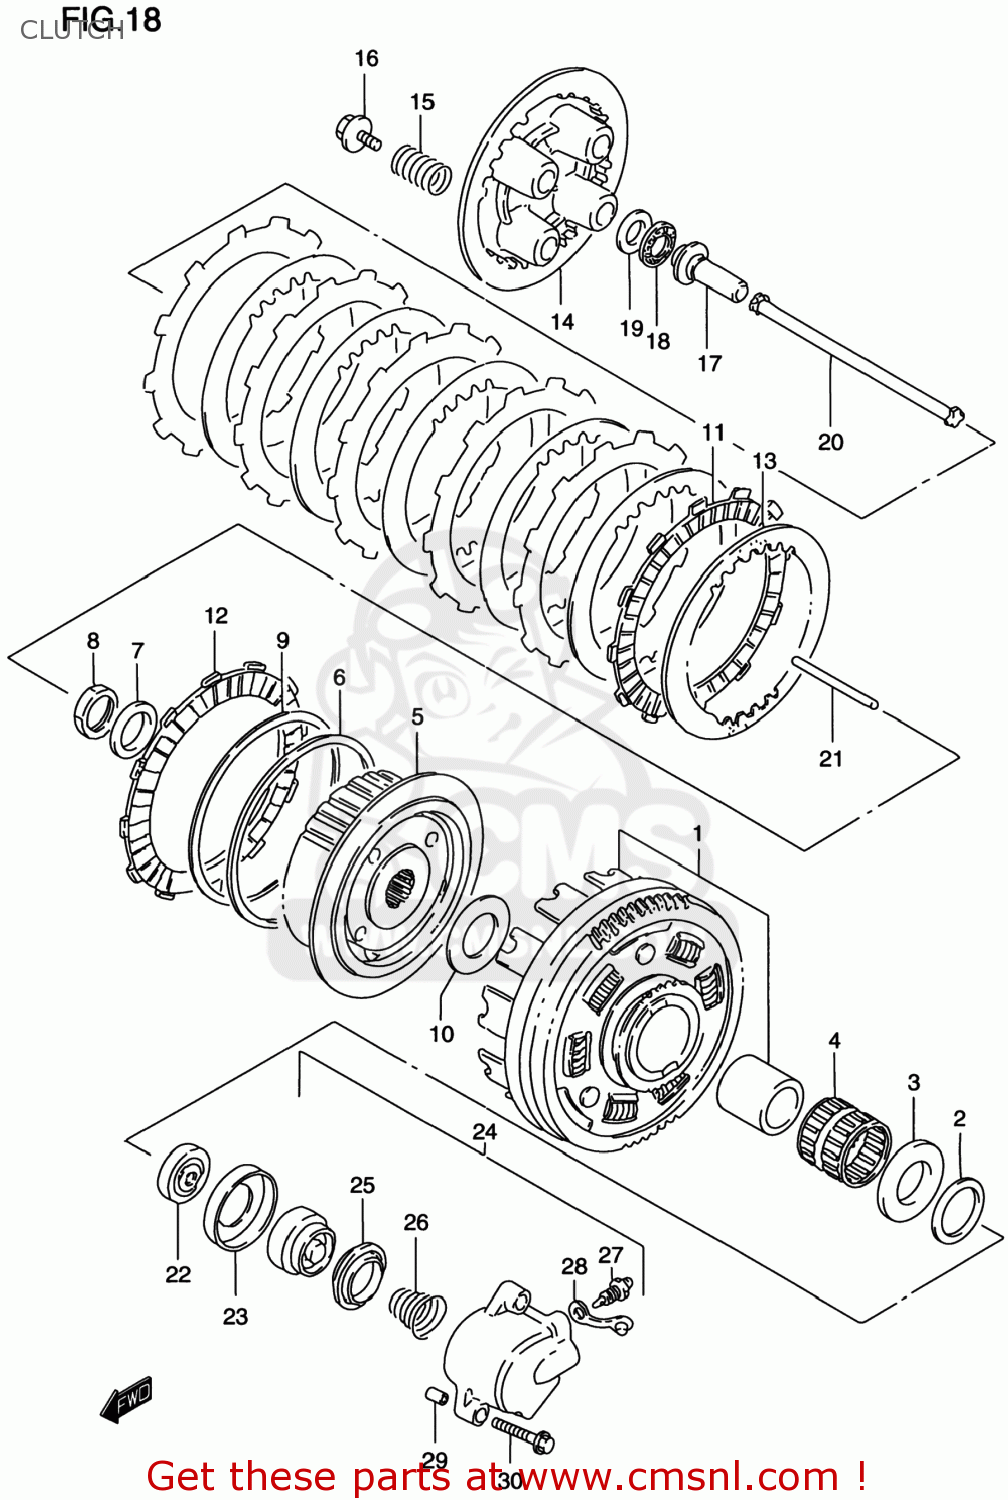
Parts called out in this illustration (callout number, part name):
1	GEAR ASSY,PRIMARY(NT:71)
2	SPACER(25X38X6.5)
3	WASHER(25X50X2.5)
4	BEARING(35X40X35.8)
5	HUB COMP,CLUTCH SLEEVE
6	SEAT,WAVE WASHER(T:1.4)
7	WASHER
8	NUT
9	WASHER
10	WASHER(25X50X2.5)
11	PLATE,CLUTCH DRIVE (NAS)
12	PLATE,CLUTCH DRIVE(T:3.5) (NAS)
13	PLATE,CLUTCH DRIVEN(T:1.6) (NAS)
14	DISC,CLUTCH PRESSURE
15	SPRING
16	BOLT(6X20)
17	PIECE,CLUTCH PUSH
18	BEARING(15X28X2)
19	WASHER(15.5X28X1)
20	ROD,CLUTCH
21	ROD,CLUTCH PUSH,L
22	SEAL,OIL(6X34X11)
23	RETAINER,CL PUSH ROD OIL SEAL
24	CYLINDER,CLUTCH RELEASE
25	CUP,CLUTCH CYLINDER
26	SPRING,CLUTCH CYLINDER
27	BLEEDER
28	CAP,BLEEDER
29	PIN
30	BOLT
